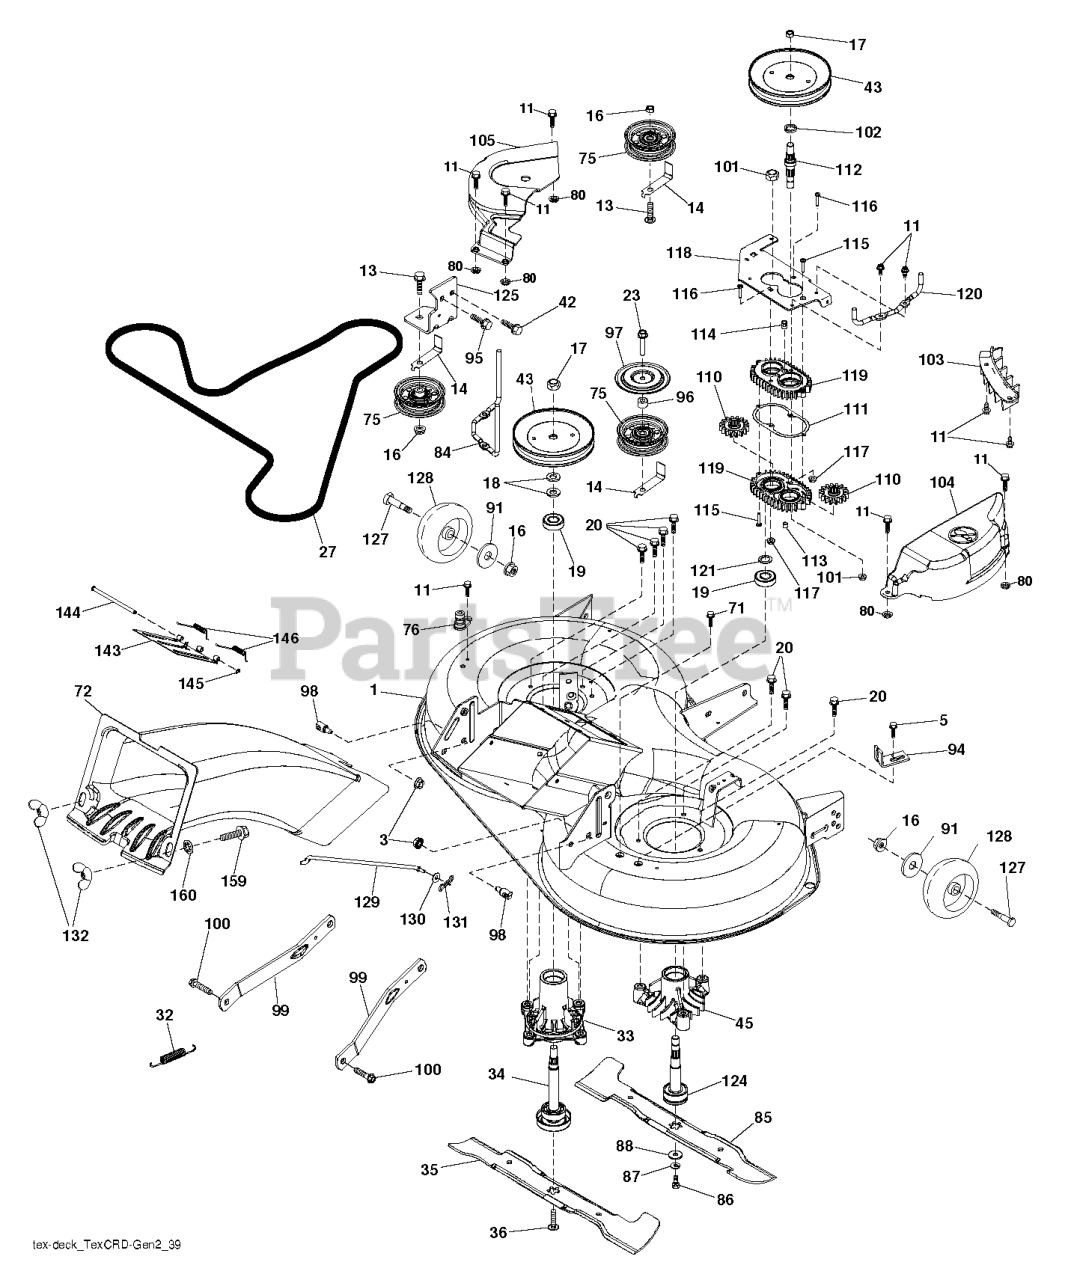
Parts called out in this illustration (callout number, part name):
1	DECK.SVC.WLDT.97EL.TCRD.EZ.498
3	NUT LOCK HEX FLANGE 5/16-18
5	BOLT.5/16HEX.WHS.HD
11	SCREW.1/4-20X5/8
13	BOLT.3/8-16X1.50
14	KEEPER, BELT IDLER
16	NUT LOCK FLG 3/8-16 UNC
17	NUT.FLANGE.LOCK.TOP
18	WASHER.SPACER.MANDREL
20	SCREW, WASHER HEAD
23	SCREW LT
27	BELT 97CM ELECTRIC
32	SPRING 107CM & 97CM ELECTRIC D
33	RP.HOUSING.MANDREL.4PT.
34	SHAFT.ASM.MDRL.N/GREASE.38
35	BLADE.3N1.LH.CRD.97
36	BOLT.WASHER.ASM.7/16-2
42	SCREW
43	PULLEY.MANDREL.5.0.PD.38"
45	HOUSING.MANDREL.44/46" VENT
71	SCREW 3/8-16X1/2
72	CHUTE REAR CRD UPPER CHUTE TEX
75	FLAT IDLER PULLEY
76	PORT.WASHOUT
80	PALNUT 1/4
84	BELT KEEPER.MANDREL.38"COATED
85	BLADE.3N1.RH.CRD.97
86	BOLT.3/8-24X1.25GR8. LHTHRD
87	LOCKWASHER
88	WASHER.BLADE
91	WASHER
94	BRKT.CLUTCH.CABLE
95	SCREW, 3/8-16X3/4
96	SPACER
97	PROTECTOR
98	STUD.FASTNER.W/ANTI-ROTATE
99	ARM.SUSPENSION.MOWER.R
100	BOLT.SHOULDER
101	NUT.CROWNLOCK.9/16 -18.UNC
102	SPACER BEARING
103	GUARD GUARD FRONT VENT
110	CRD.SPUR.GEAR
111	GASKET GASKET GEARCASE
112	SHAFT SHAFT. CRD GEARCASE ADAP
113	PLUG PLUG OIL
114	VALVE VALVE RELIEF
115	SCREW
116	BOLT.CARIGE.SS.1/4-20X1.75GR5
117	NUT T
118	ARM ARM CLUTCHING
119	GEARCASE GEARCASE SUBASM
120	BRACKET KEEPER BELT RH
121	WASHER WASHER
124	MANDREL SHAFT NON/GREASE
125	BRACKET BRACKET IDLER CHASSES
127	BOLT.SHOULDER.3/8-16X3-5/8.
128	RP WHEEL. GUAGE RALLY
129	ROD.ANTI.SWAY.48/54"K4
130	WASHER
131	PIN.COTTER.5/16.BOW TI
132	KNOB.HANDLE.3/8.TRI-POINT.BLAC
143	DOOR
144	PIN PIN.HINGE
145	E-RING.5/16"
146	SPRING SPRING: EZ MULCH DOOR
159	BOLT
